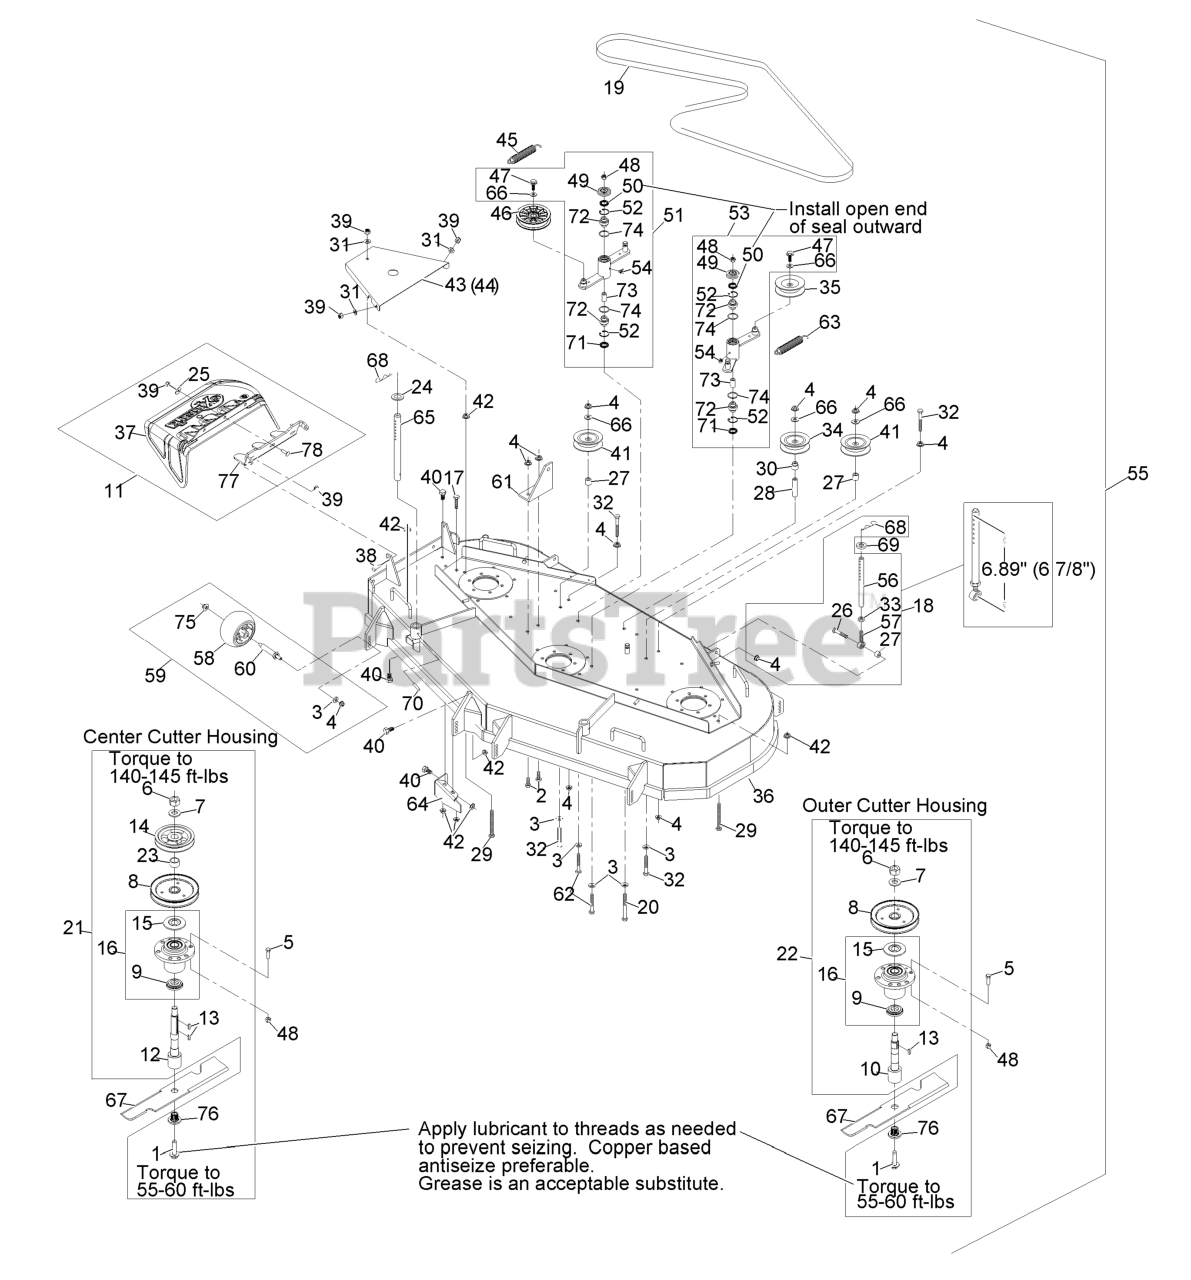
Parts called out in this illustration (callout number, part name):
1	SCREW,SEMS 1/2-20 X 2.19
2	SCREW-HH
3	WASHER-BELLEVILLE
4	NUT-HHF, WHIZ
5	SCREW-HH
8	SHEAVE,BLADE DRIVE 6.30
9	SPACER-GUARD, BOTTOM
10	KIT, SPLINED SPINDLE 103-
11	ASM,FMD DISCHARGE CHUTE
12	KIT, SPLINED SPINDLE 103-
14	SHEAVE,BLADE DRIVE
15	GUARD-BEARING, TOP
16	KIT, CUTTER HOUSING
17	SCREW-HH
18	KIT,SUPPORT LINK W/PIN
19	BELT,MULE DRIVE
20	SCREW-HH
21	ASM, CUTTER HSG FMD604CTR
22	ASM, CUTTER HSG COMPLETE
23	SPACER,TUBE
24	SPACER-DECK SUPPORT
25	WASHER-FLAT
26	SCREW-HH
28	SPACER-ANCHOR, CLUTCH
29	BOLT,TAP HH
30	BUSHING,IDLER
31	WASHER-FLAT
32	BOLT-CARR
33	NUT-HJ
34	PULLEY-IDLER
35	PULLEY-IDLER
36	ASM, DECK W/ DECALS FMD60
37	CHUTE,DISCHARGE
38	SCREW-HH
39	NUT-LOCK, NI
40	SCREW-HH
41	IDLER,PULLEY
43	SHIELD,BELT RH
44	SHIELD,BELT LH
45	SPRING-EXTENSION
46	PULLEY-IDLER, FLAT
47	SCREW-HHF
48	NUT-LOCK, NI
49	GUARD-TOP
50	SEAL-LIP, SINGLE
51	KIT, IDLER ARM W/BEARINGS
52	RING-SNAP
53	KIT, IDLER ARM W/BEARINGS
54	FITTING-GREASE, 90 DEG
55	Complete Deck Assy
56	LINK,SUPPORT
57	BALLJOINT
58	ROLLER-SCALP, ANTI
61	BRACKET,SPRING ANCHOR
62	SCREW-HH
63	SPRING-EXTENSION
64	BAFFLE,DISCHARGE
65	ROD,DECK SUPPORT
66	WASHER-FLAT
68	PIN,HAIR COTTER
71	SEAL-LIP, DOUBLE
72	BEARING-SPHERICAL
73	BUSHING-LEVER, LIFT
75	Nut-Nyloc 3/8-16 Flg
76	BUSHING,SPLINED
77	BRACKET, DISCHARGE CHUTE
78	SCREW-CARR
